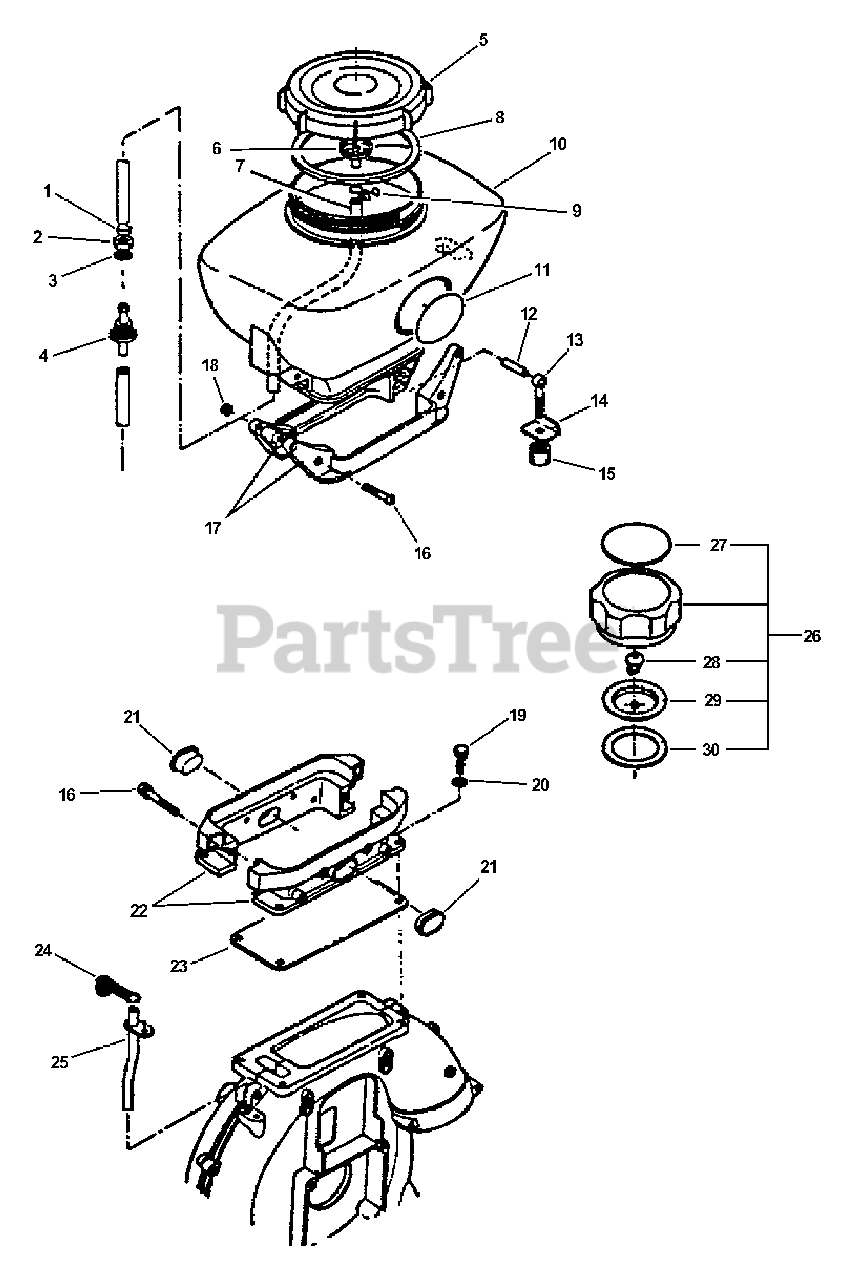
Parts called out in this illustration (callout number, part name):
1	CLAMP
2	NUT - 12
3	WASHER - 12
4	CONNECTOR, PIPE
5	CAP, CHEMICAL TANK
6	VENT, TANK
7	HOSE, FLUID
8	GASKET, CAP
9	CLAMP
10	TANK, CHEMICAL
11	LABEL
16	SCREW - 5X30
17	HOLDER
19	BOLT - 6X20
20	WASHER - 6
22	CLAMP KIT
25	HOSE, AIR
26	CAP ASSY
27	LABEL - FUEL MIX
29	HOLDER, VENT
30	GASKET, CAP
